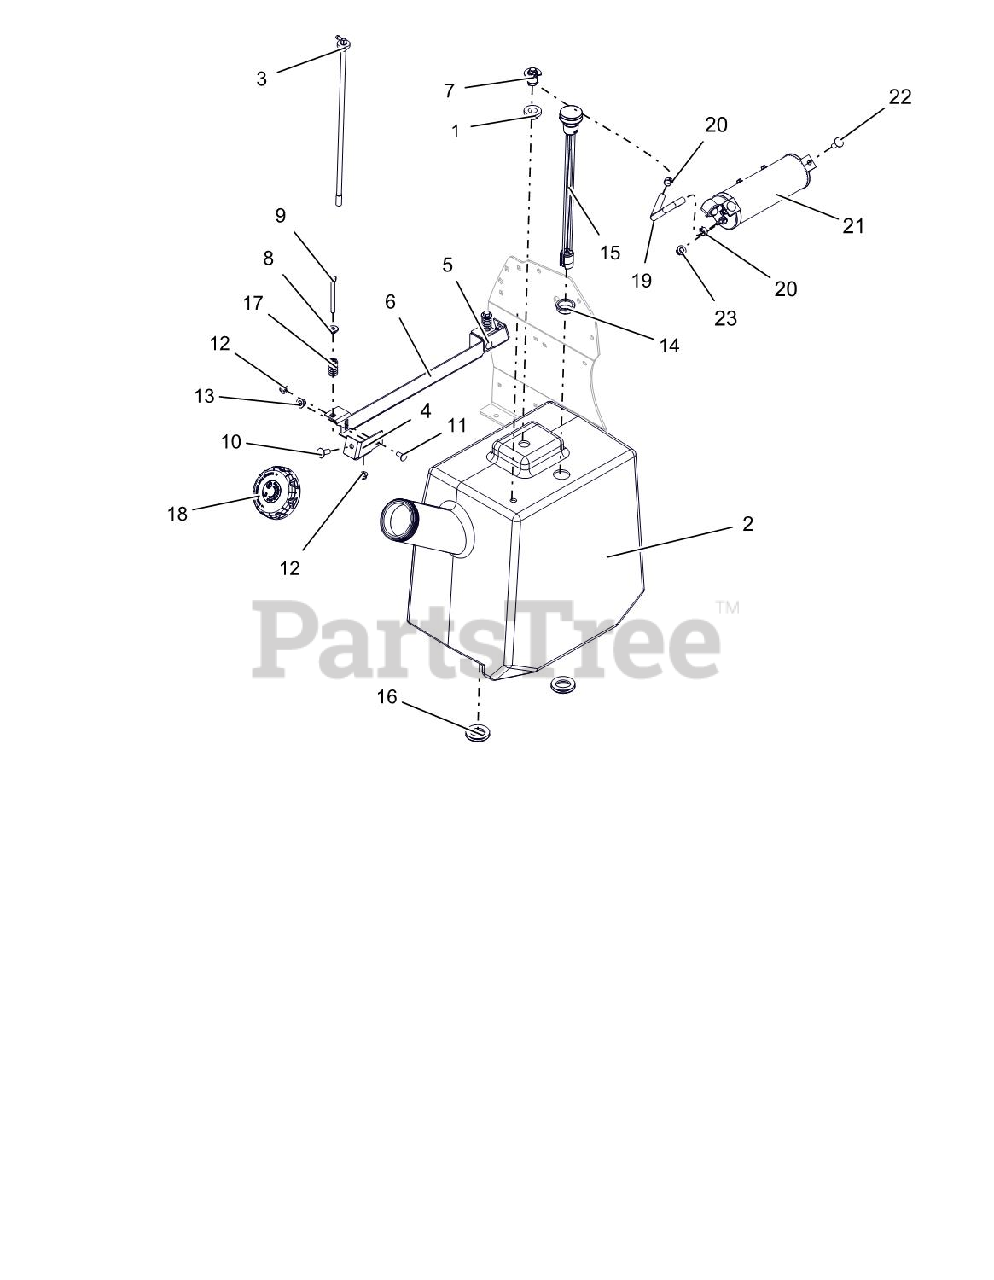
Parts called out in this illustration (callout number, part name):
1	GROMMET, REMOTE VENT NITRILE
2	TANK, PROSTANCE FUEL
3	ASS'Y, PROSTANCE FUEL PICK-UP
4	MOUNT, FUEL TANK HOLD DOWN-RH
5	MOUNT, FUEL TANK HOLD DOWN-LH
6	HOLDDOWN, FUEL TANK
7	VALVE, 2-WAY
8	BSHG-FLG .32X.500X.344X.880
9	BLT-HEX .31-18X3.25 GR5 YWZC
10	BLT-RDHDSHSQNK.38-16X1.0 G5YZ
11	BLT-RDHDSQNK .31-18X.75 G5YZ
12	NUT-LK-NYL-FLG .31-18 YWZC
13	NUT-LK-NYL-FLG .38-16 YWZC
14	GROMMET, FUEL GAUGE
15	GAUGE, REMOTE FUEL SEALED 15"
16	GROMMET 1.25ID X 1.5OD
17	SG-COMP .125X.781X1.250
18	CAP, FUEL NONVENT AUTOLOCK
19	HOSE, .25 LOW-PERM BULK GAS
20	CLAMP, FUEL LINE
21	CANISTER, CARBON 9.3G CAP.
22	BLT-RDHDSQNK .38-16X1.00 G5YZ
23	NUT-LK-NYL-FLG .38-16 YWZC
